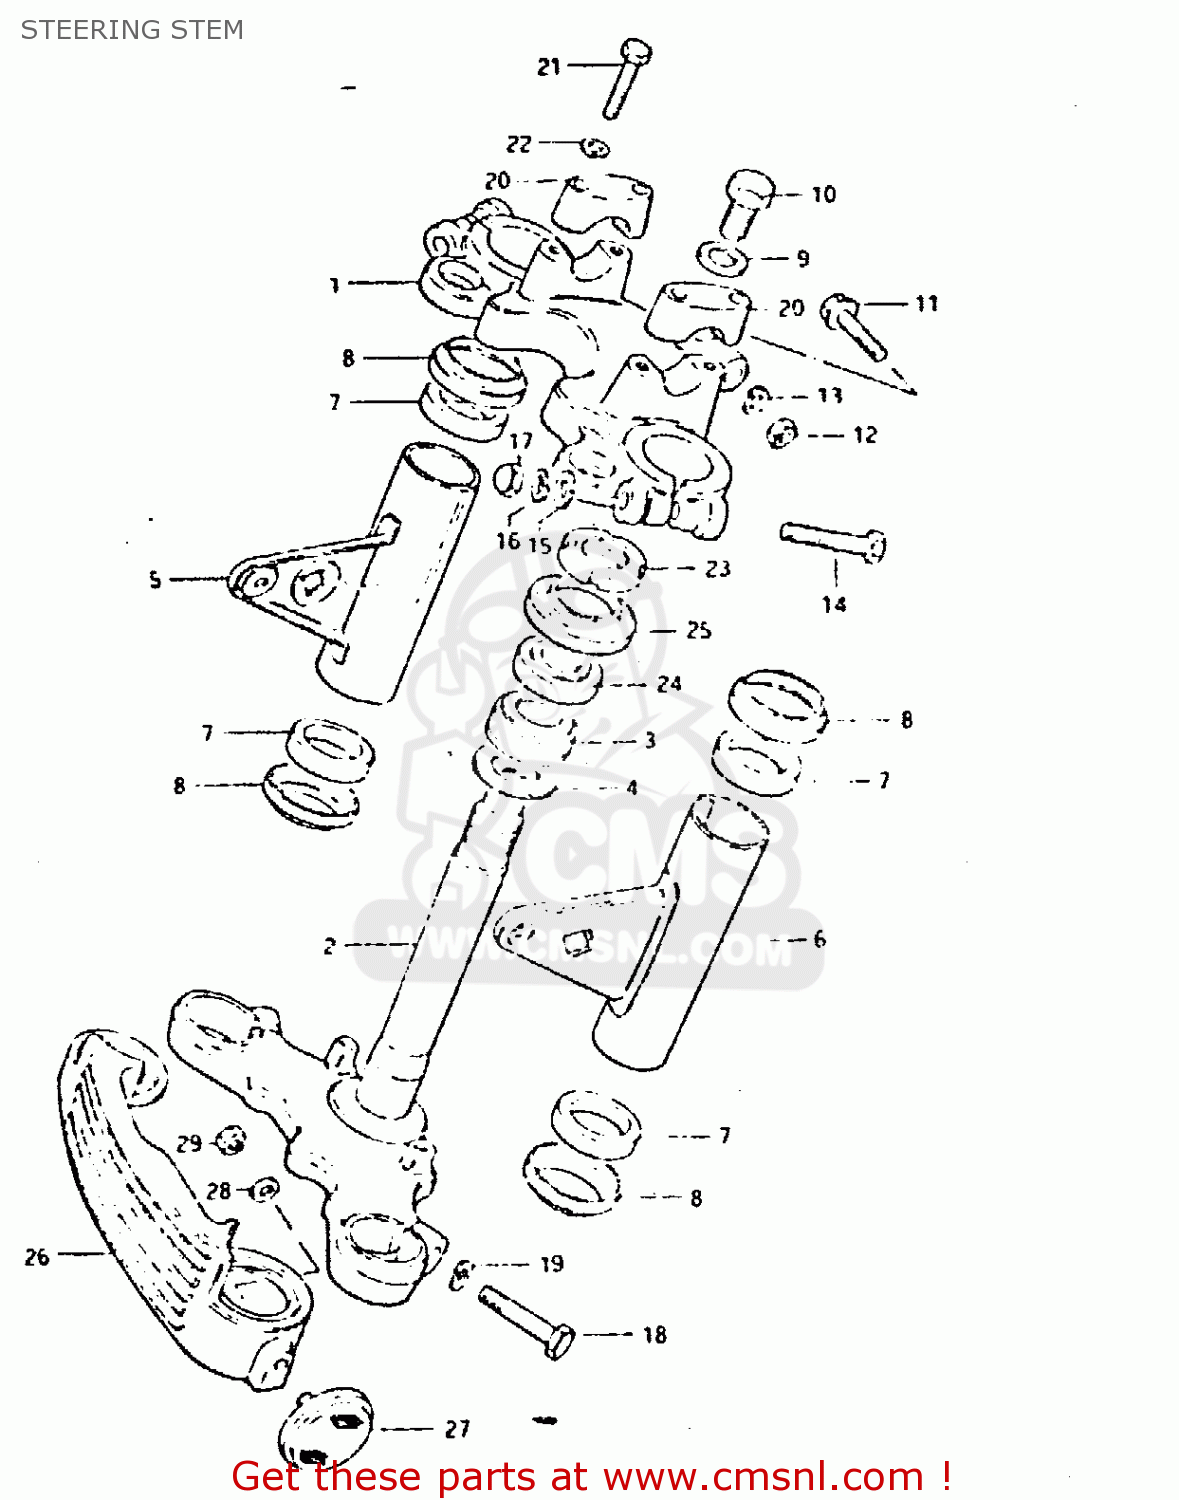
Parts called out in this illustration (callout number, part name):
1	HEAD,STEERING STEM
2	STEM,STEERING
3	BEARING
4	WASHER,THRUST
5	BRACKET,HEADLAMP,RIGHT
6	BRACKET,HEADLAMP,LEFT
7	CUSHION,HEADLAMP BRACKET
8	CAP,HEADLAMP BRACKET
9	WASHER
10	BOLT(12X20)
11	BOLT
12	NUT
13	LOCK WASHER
14	BOLT 10X55
15	WASHER
16	LOCK WASHER
17	NUT
18	BOLT 10X40
19	LOCK WASHER
20	HOLDER,HANDLE UPR
21	BOLT
22	LOCK WASHER
23	NUT,STEERING STEM(25X44X10)
24	TAPER,ROLLER BEARING
25	DUST SEAL,STEERING,UPPER
26	COVER,FRONT FORK
27	REFLEX REFLECTOR,RR
28	WASHER
29	NUT
